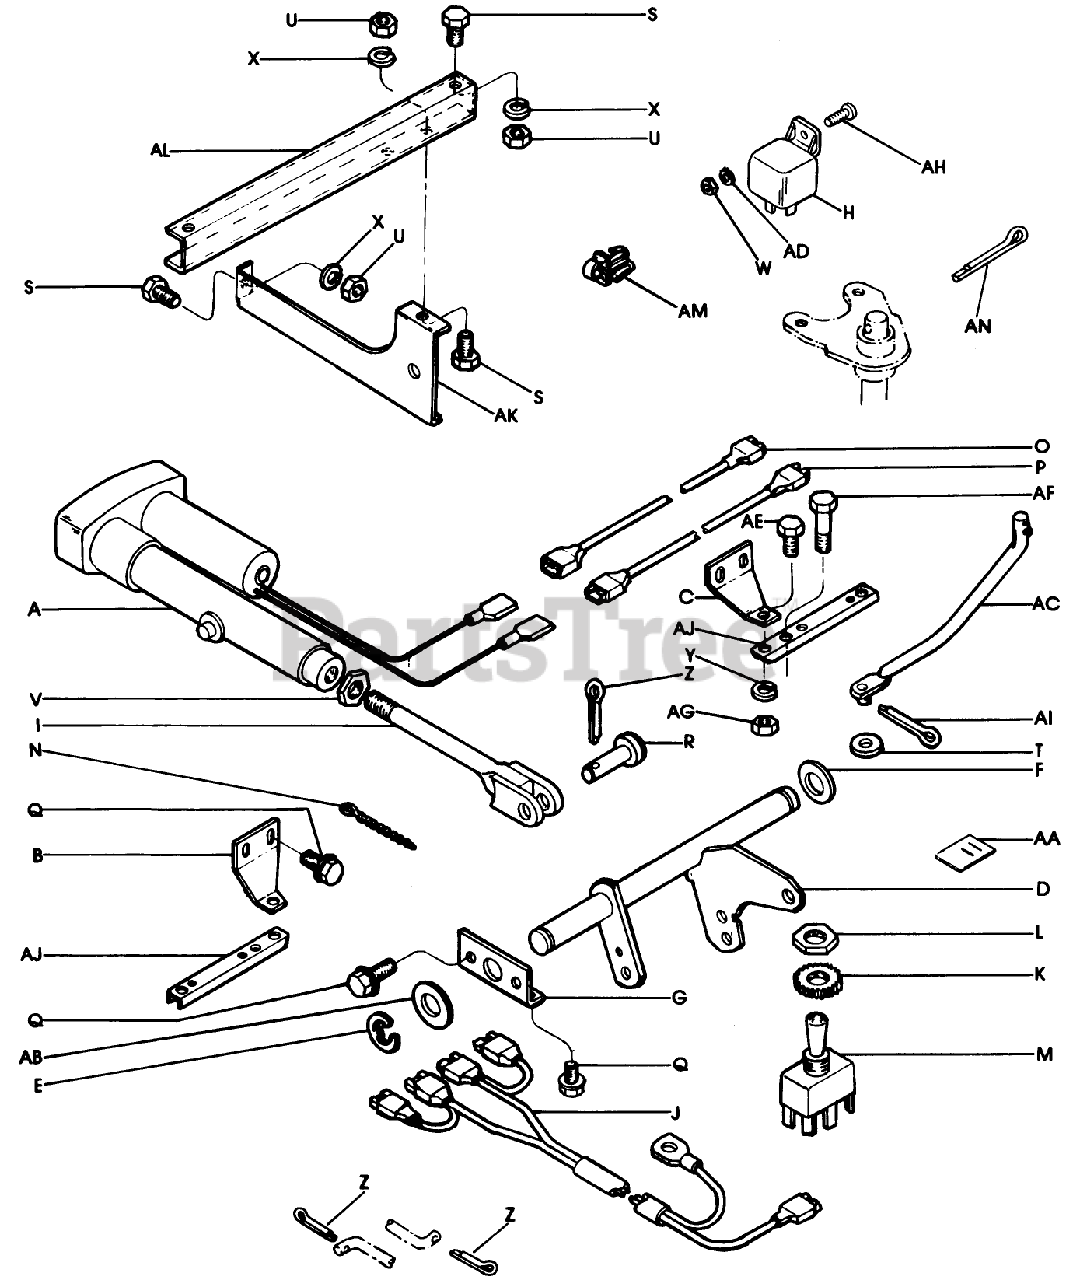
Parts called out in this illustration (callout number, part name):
B	Brace-R.H.
C	Brace-L.H.
X	Lock Washer 5/16 Plated
